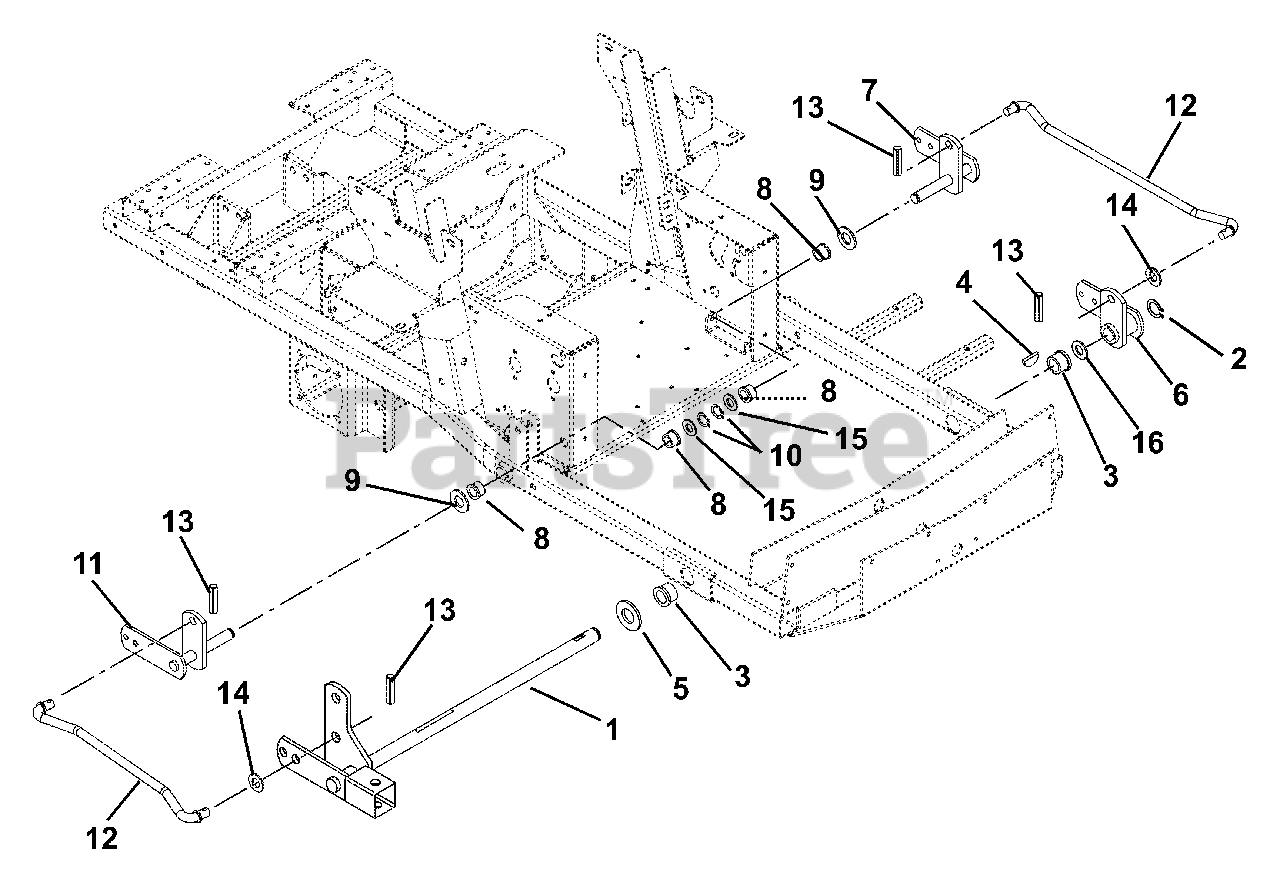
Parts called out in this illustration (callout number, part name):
1	MOWER LIFT
2	RG-RTNG-EXT 1.00X.078
3	BSHG-FLG1.020X1.385X.75X1.75NY
4	KEY-WDRF .25X1.00 HRD #15
5	WSHR-FL-STL 1.063X2.00X.134
6	WMT, FRONT MOWER LIFT-LH
7	WMT, REAR LIFT ARM -LH
8	BSHG-FLG .762X1.0X.580X1.48 NY
9	WSHR-HDND-THRST .758X1.23X.031
10	RG-RTNG-EXT .689X.078
11	WMT, REAR LIFT ARM - RH
12	ROD, LIFT ASSIST 19.35"
13	PIN-ROLL .250X1.25 STNLESS STL
14	WSHR-FL-STL .630X1.250X.062 YZ
15	WSHR-FL-STL .755X1.25X.125 YZ
16	WSHR-HDND-THRUST 1.00X1.55X.03
